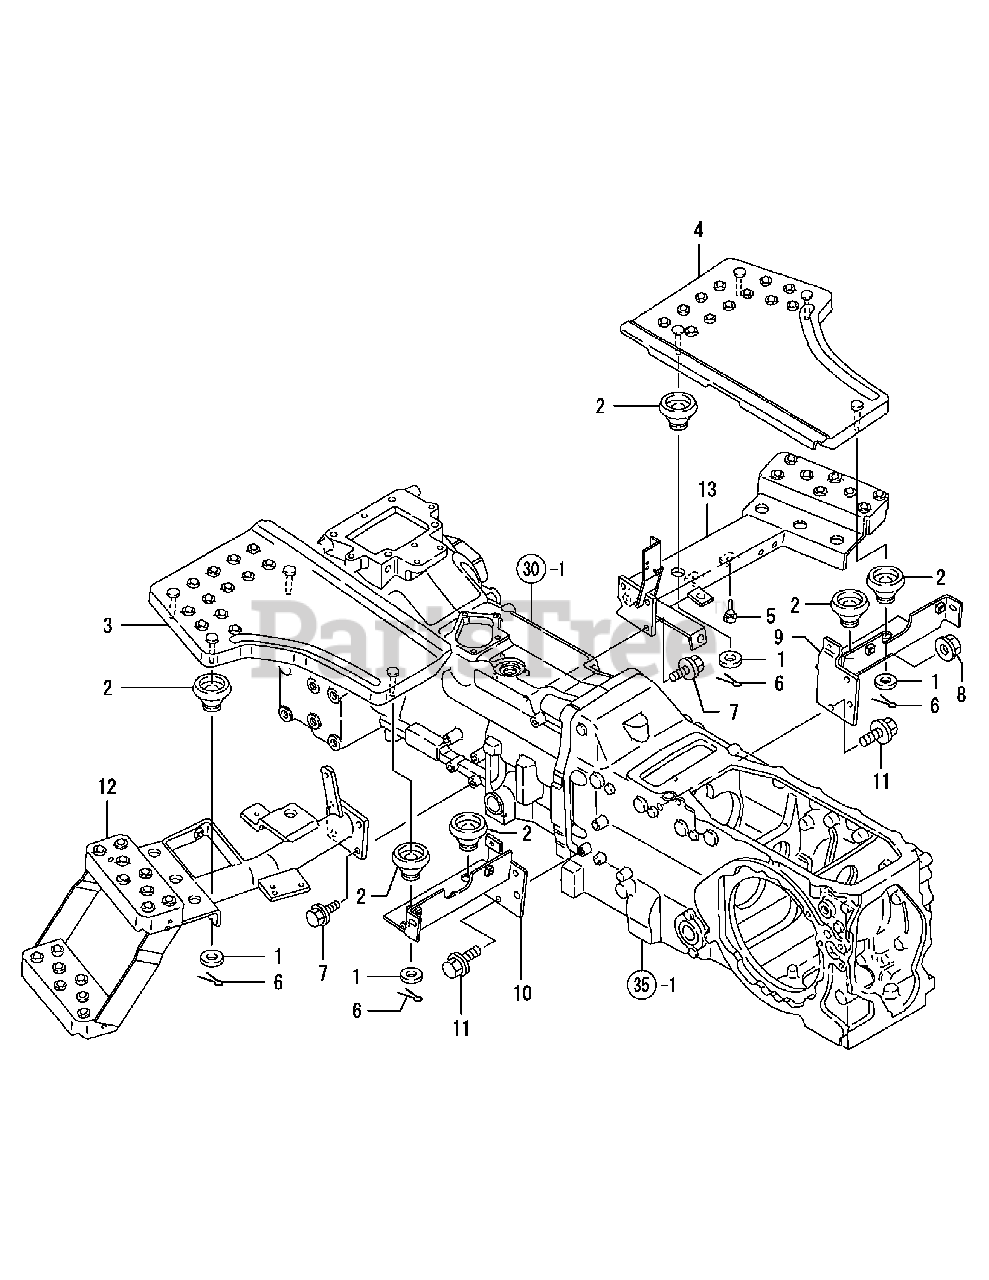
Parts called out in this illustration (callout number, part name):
2	RUBBER,STEP GROMMET
3	FOOTREST, L.H.
4	FOOTREST, R.H.
5	STOPPER, PEDAL
6	COTTER PIN 2.5X30
7	BOLT M 8X 20 PLATED
8	NUT W/WASHER 8
9	STAY, CUSHION R
10	STAY, CUSHION L
11	BOLT M 8X 16 PLATED
12	STAY, STEP L.H
13	STAY, STEP R.H
